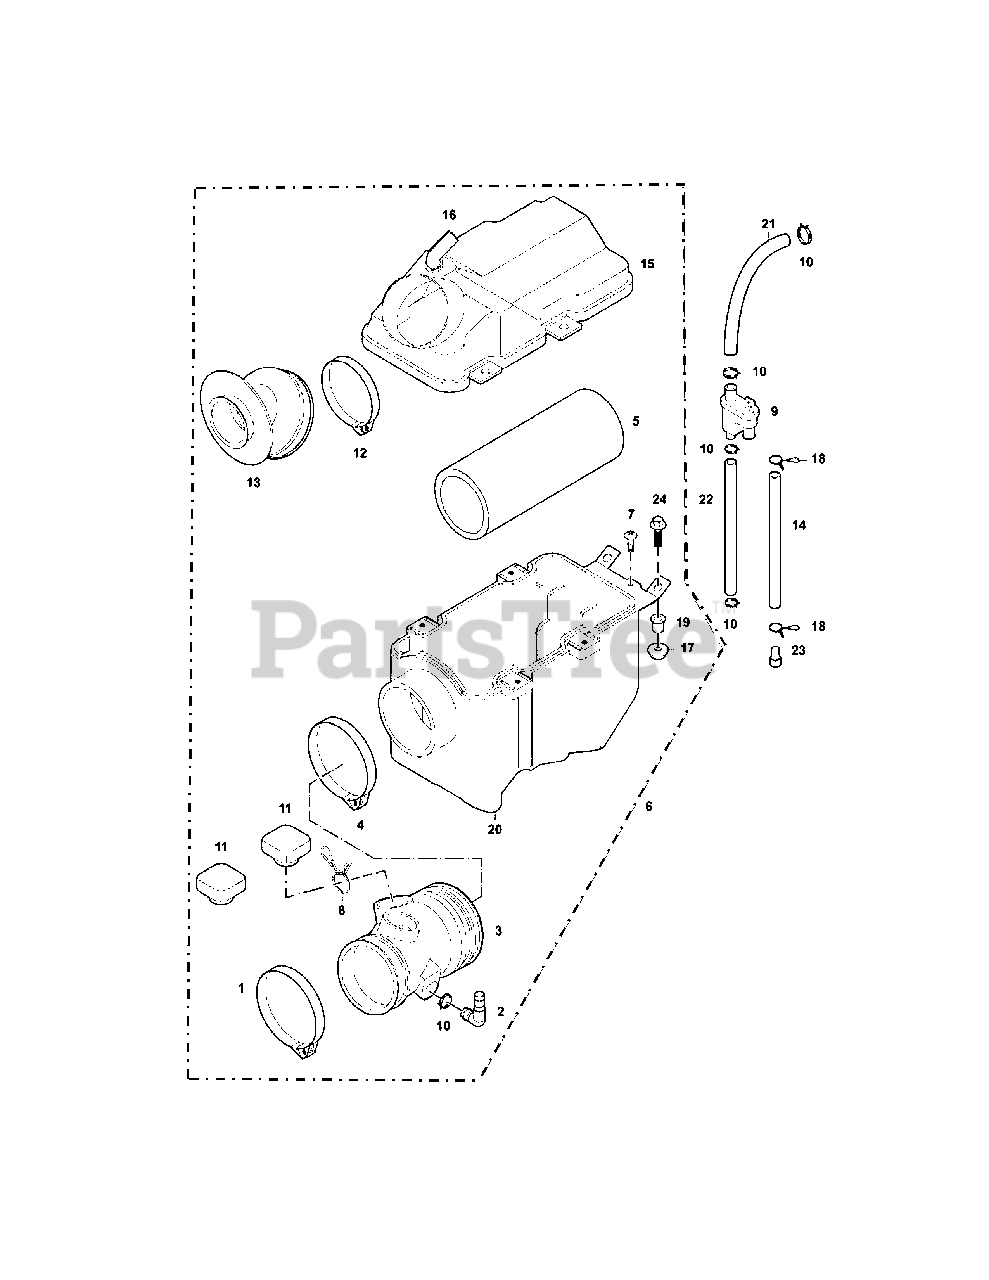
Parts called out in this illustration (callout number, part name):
1	Screw Hoop 60-80
2	Rubber Pipe III 11x15x50-50
3	Air-Out Pipe
4	Clamp IV
5	Air Filter Element
6	Air Filter Assy
7	Cross Recessed Plate Head Screw M5x12
9	Oil & Air Separator
11	Connecting Pipe, Muffler
12	Clamp IV
13	Primary Air Filter Outlet Pipe
14	Used Oil Collection Pipe
15	Air Filter Cover
17	Hexagon Flange Nut M6
18	Steel Clip 12
19	Bushing 6.5x9x22x6.5
20	Air Filter Shell
21	Rubber Pipe 11x15x140-90
22	EGR Tube 11x15x100
23	Block, Used Oil Pipe
24	Hexagon Flange Bolt M6x20
